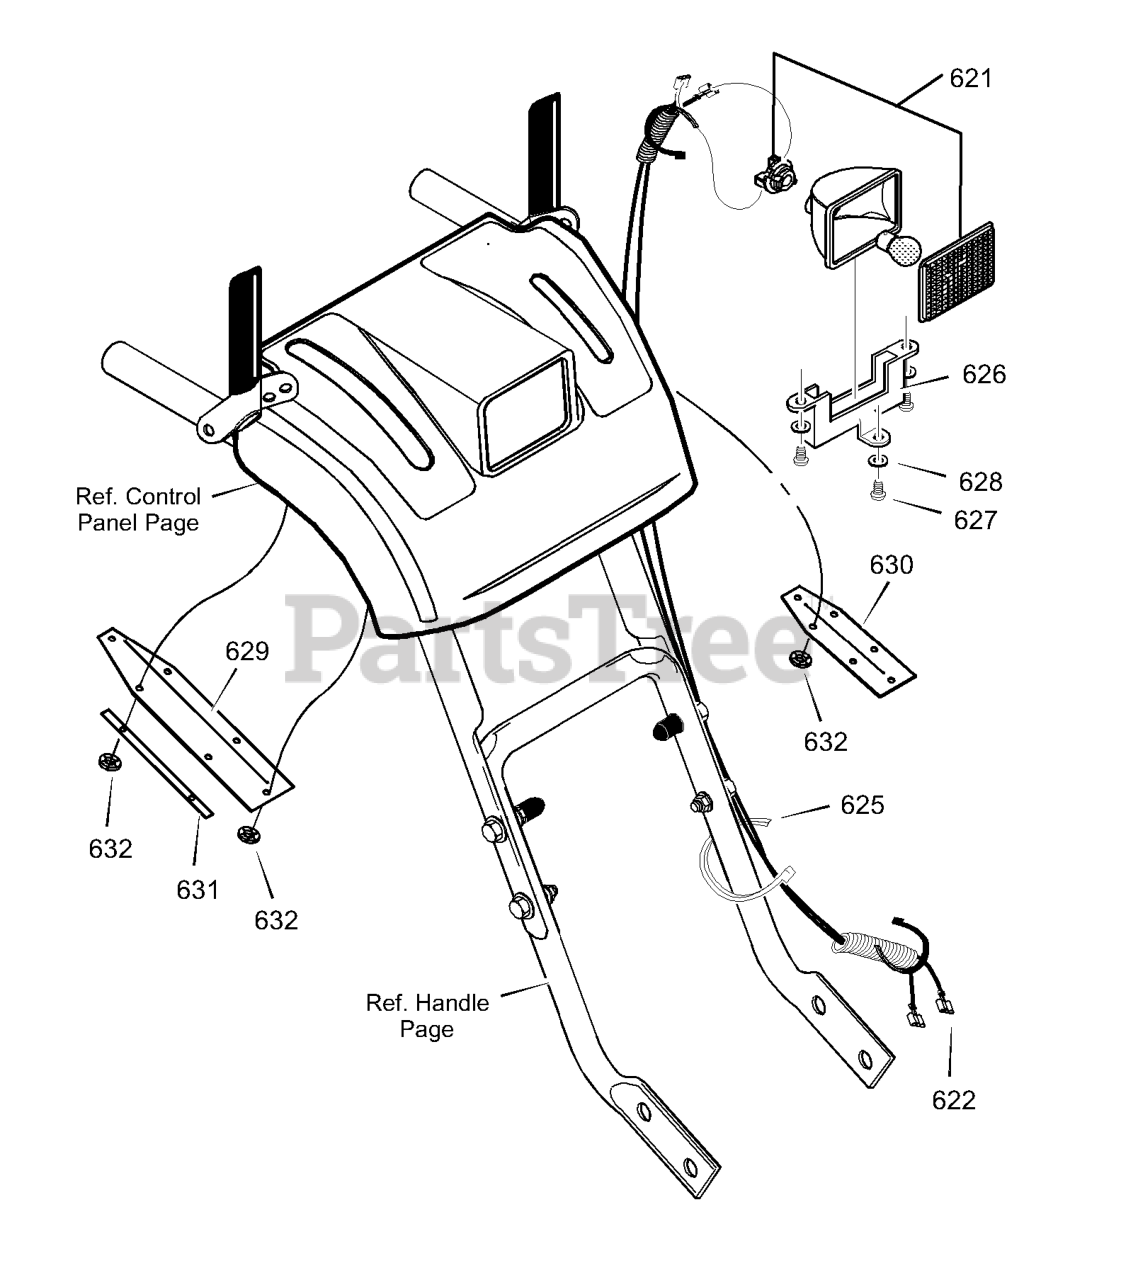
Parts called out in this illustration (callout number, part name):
622	HARNESS, WIRE
625	TIE, CABLE
626	BRACKET
627	SCREW #8 X .50
628	WASHER, FLAT
632	NUT, PUSH
